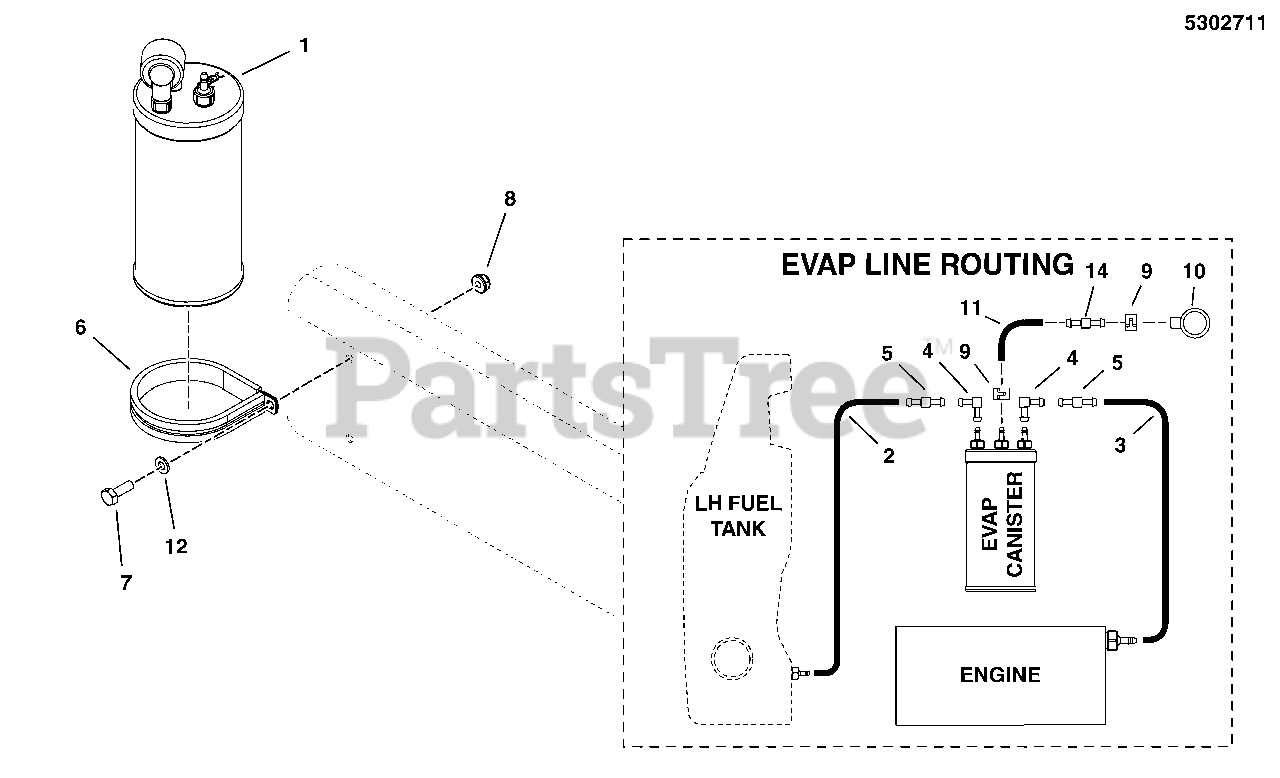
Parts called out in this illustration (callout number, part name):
1	CNSTR, CARB, 6 GAL
2	HOSE, VAPOR, 5MM ID, 27.00 LG
3	HOSE, VAPOR, 5MM ID, 11.50 LG
4	FITTING, 90 DEG, 3/16X3/16, SANTOPRENE
5	FITTING, STRAIGHT, 3/16X3/16, PLASTIC
6	CLAMP, 3" ID, CUSHIONED, STAINLESS
7	BOLT, 1/4-20 X 3/4 GD5 YZ
8	NUT, 1/4-20 HEX NYLOCK FLANGE
9	CLAMP, HOSE
10	DUST FILTER, Cannister
11	HOSE, FORMED, EVAP CANISTER
12	WASHER, 1/4 SAE
14	FITTING, STRAIGHT, 10MMX10MM, PLASTIC
